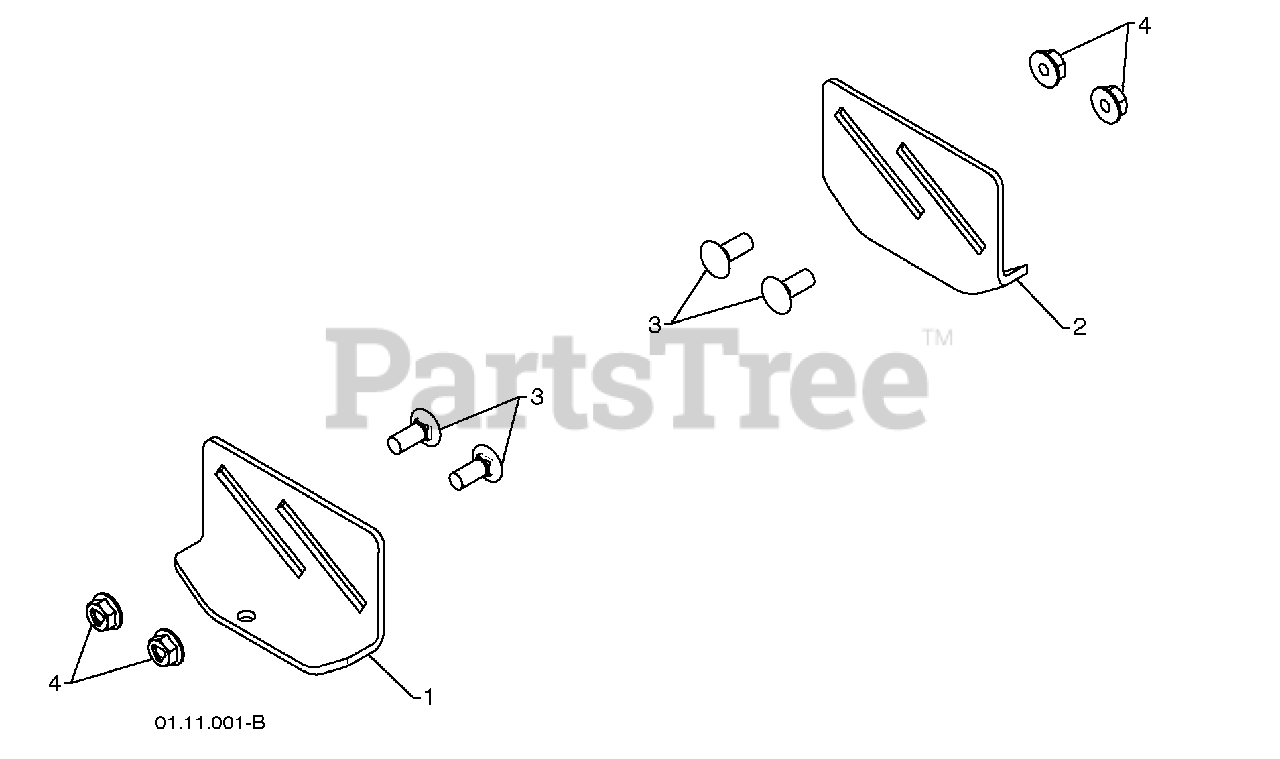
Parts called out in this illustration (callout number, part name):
1	SKID PLATE LH
2	SKID PLATE RH
3	CARRIAGE BOLT 5/16-18 X .75
4	NUT 5/16-18
